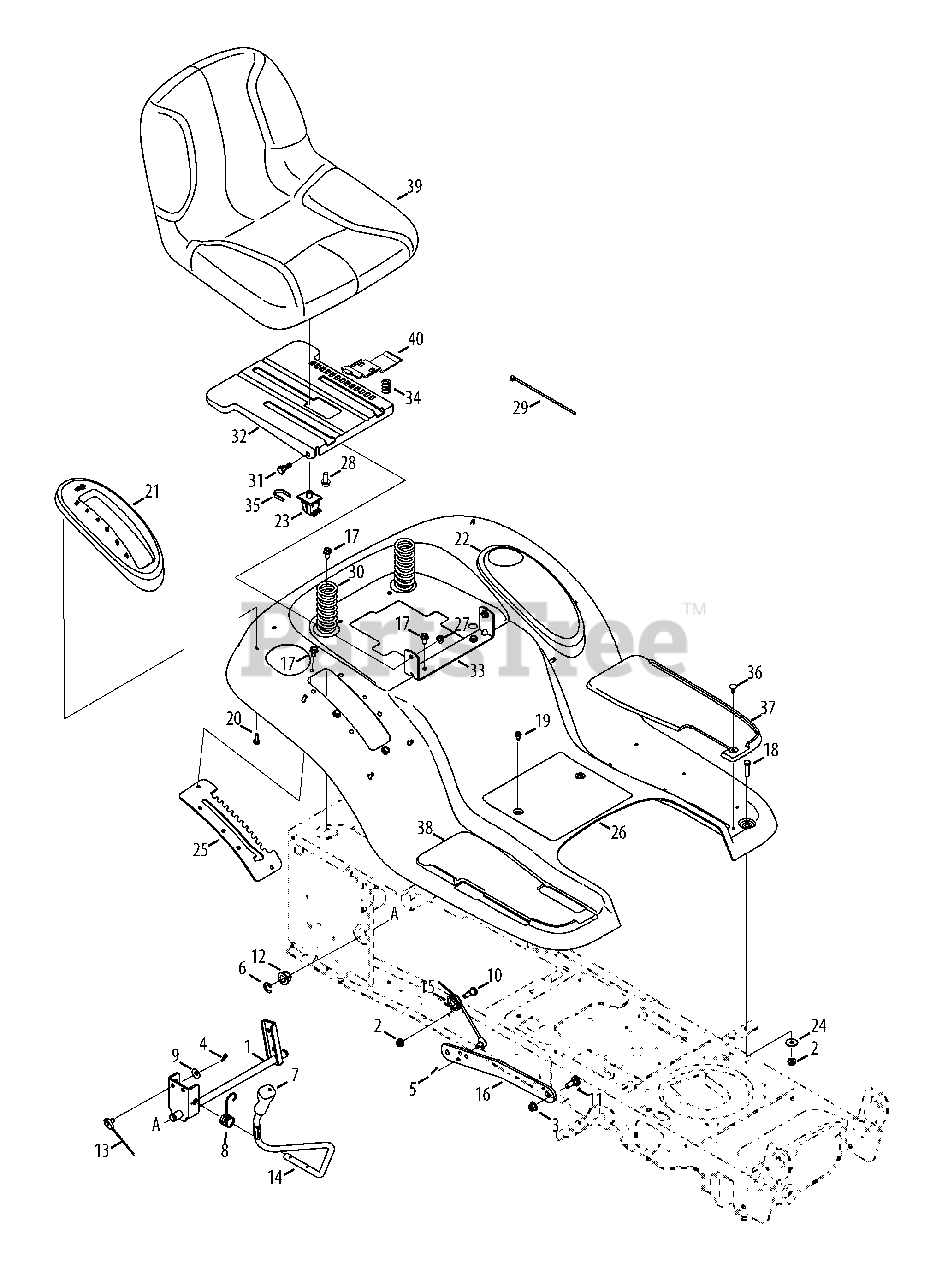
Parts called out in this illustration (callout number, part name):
1	Shaft Ass’y, Lift
2	Nut, Flange Lock, 5/16-18, Grf
3	Nut, Flange Lock, 3/8-16, Grf
4	Pin, Cotter, .072 Dia. x 1.13
5	Pin, Cotter, Bow-Tie 72, 46"
6	Ring, E Type, .625 Dia. Shaft
7	Grip, Handle, 1/2
8	Spring, Torsion
9	Washer, Spring, .401 x .870 x .063
10	Screw, Shoulder, .437 x .470, 5/16-18
11	Bolt, Shoulder, .500, 3/8-16, 46"
12	Bearing, Hex Flange
13	Cable, Lift, 16.16
14	Handle, Lift,
15	Pulley, Roller, Cable
16	Lift Link, 46"
17	Screw, Self-tapping, 5/16-18, .750,
18	Taptite Screw, 5/16-18:.750
19	Screw, Self-tapping, 1/4-20, 0.500,
20	Screw, HL, 1/4-15, 0.750,
21	Cover, Lift Lever
22	Cover w/ Cup Holder
23	Switch, Seat
24	Washer, Flat .344 x 1.00 x .063
25	Bracket, Lift, Man PTO, 6 Pos
27	Nut, Flange Lock, 5/16-18, Gr5, Sd Lk
28	Hex Head Flange, 3/8-16:.875
29	Cable, Tie, 3/16 x .05 x 7.4
30	Spring, Comprs, 1.50 x 3.90 x .200
31	Screw, Shoulder, .437 x .268, 5/16-18
32	Bracket, Mounting, Seat
33	Bracket, Pivot, Seat
34	Comp. Spring, .68 x 1.065 x .055
35	Clip, Retaining, Switch
36	Clip, Ratchet, .250 Dia
37	Pad, Foot, LH
38	Pad, Foot, RH
39	Seat, High Back
40	Seat Adjustment Lever
